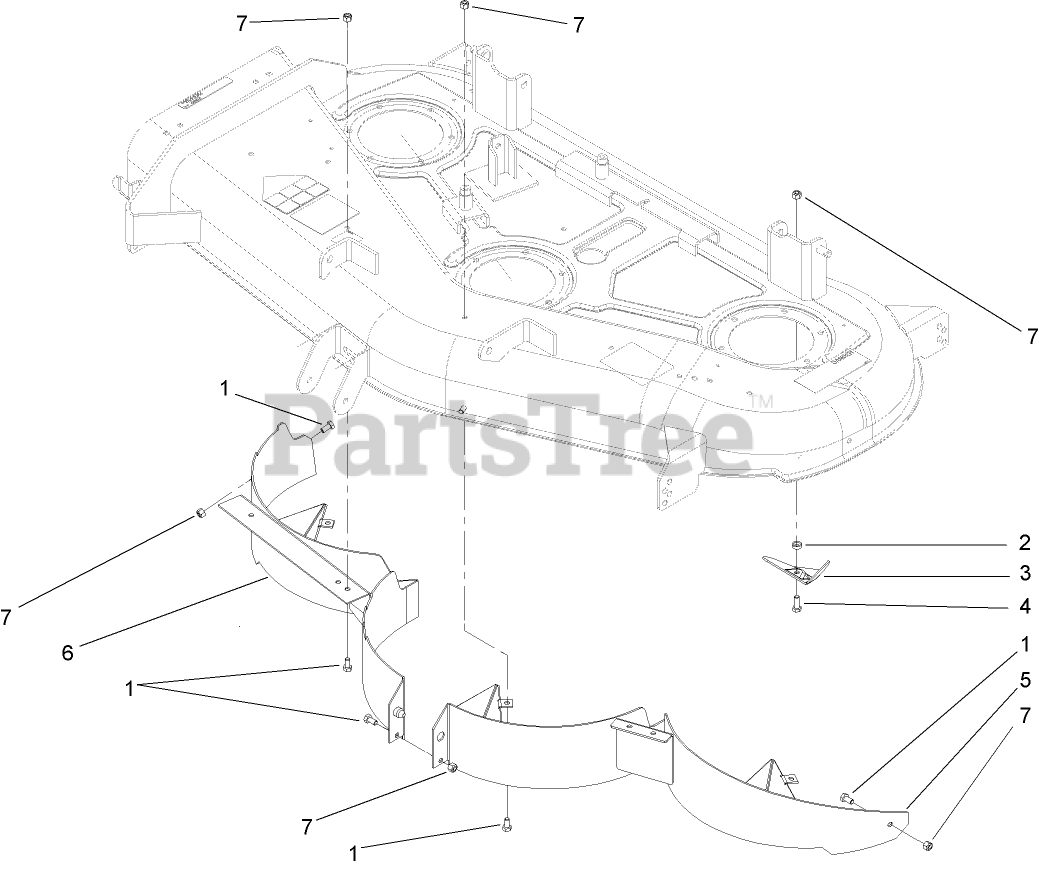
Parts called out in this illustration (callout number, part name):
1	SCREW-HH
2	SPACER
3	PLATE-KICKER
4	SCREW-HH
5	LEFT BAFFLE ASM
6	RIGHT BAFFLE ASM
7	NUT-LOCK, NI
